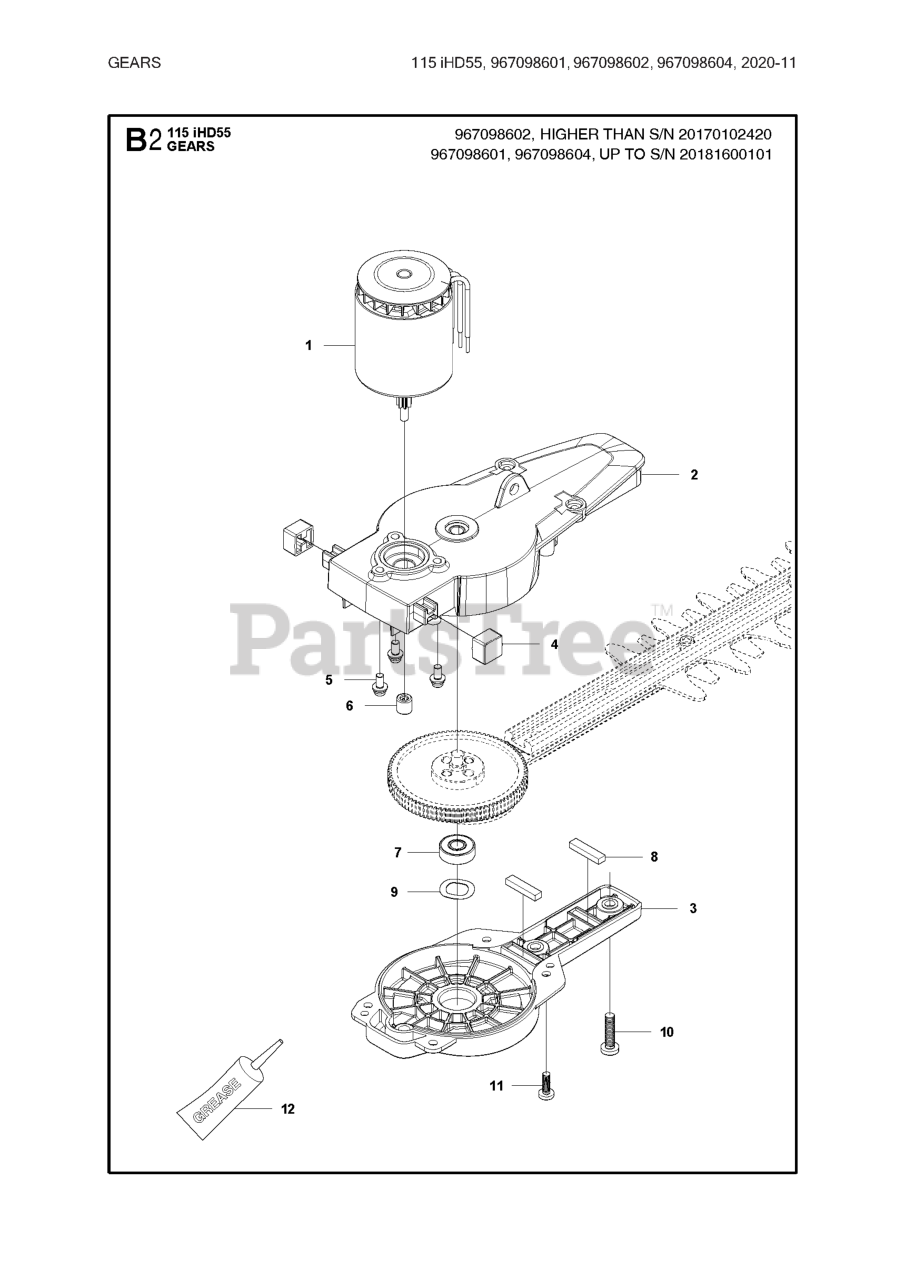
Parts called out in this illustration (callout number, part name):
1	MOTOR BLDC 115IHD55
3	COVER GEAR BOX
4	SHOCK ABSORBING
6	NEEDLE BEARING
7	BALL BEARING
8	PAD DUSTPROOF
9	SPRING WASHER
10	SCREW M5X20
11	SCREW M4X12
12	GREASE 20G HEDGE TRIMMER GEAR
